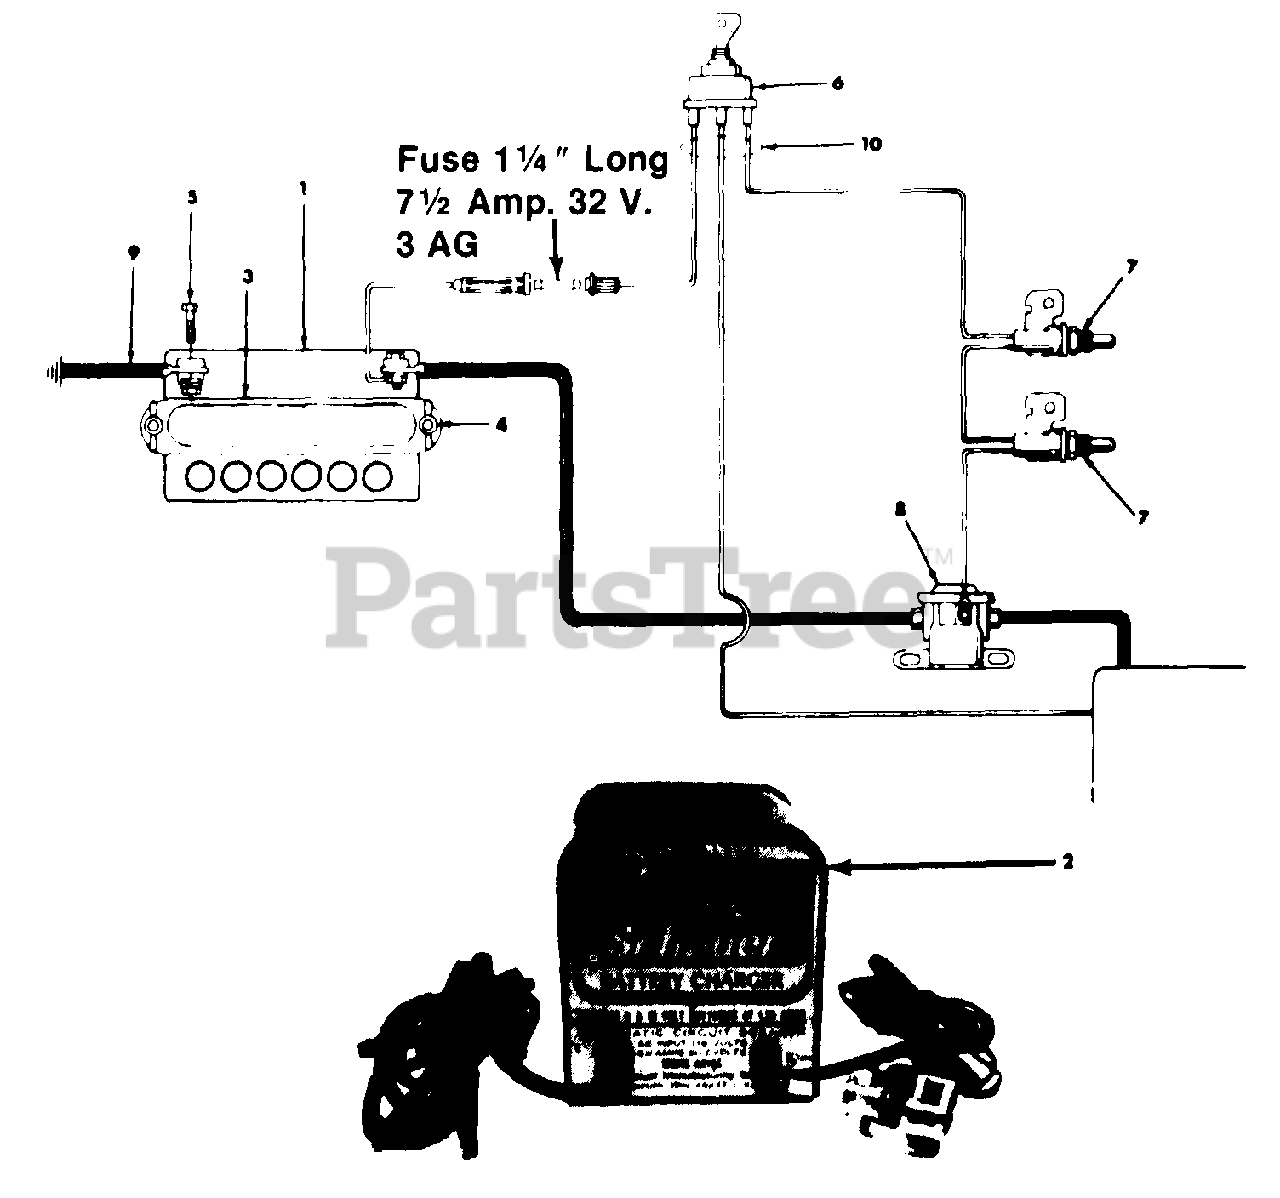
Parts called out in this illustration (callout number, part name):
3	Battery Hold Down
4	Hold Down Rod
5	Hex bolt 1/4-20 x 5/8 Lg.
6	Key Switch
7	Safety Switch
8	Solenoid
9	Ground Wire
10	Wire Harness
